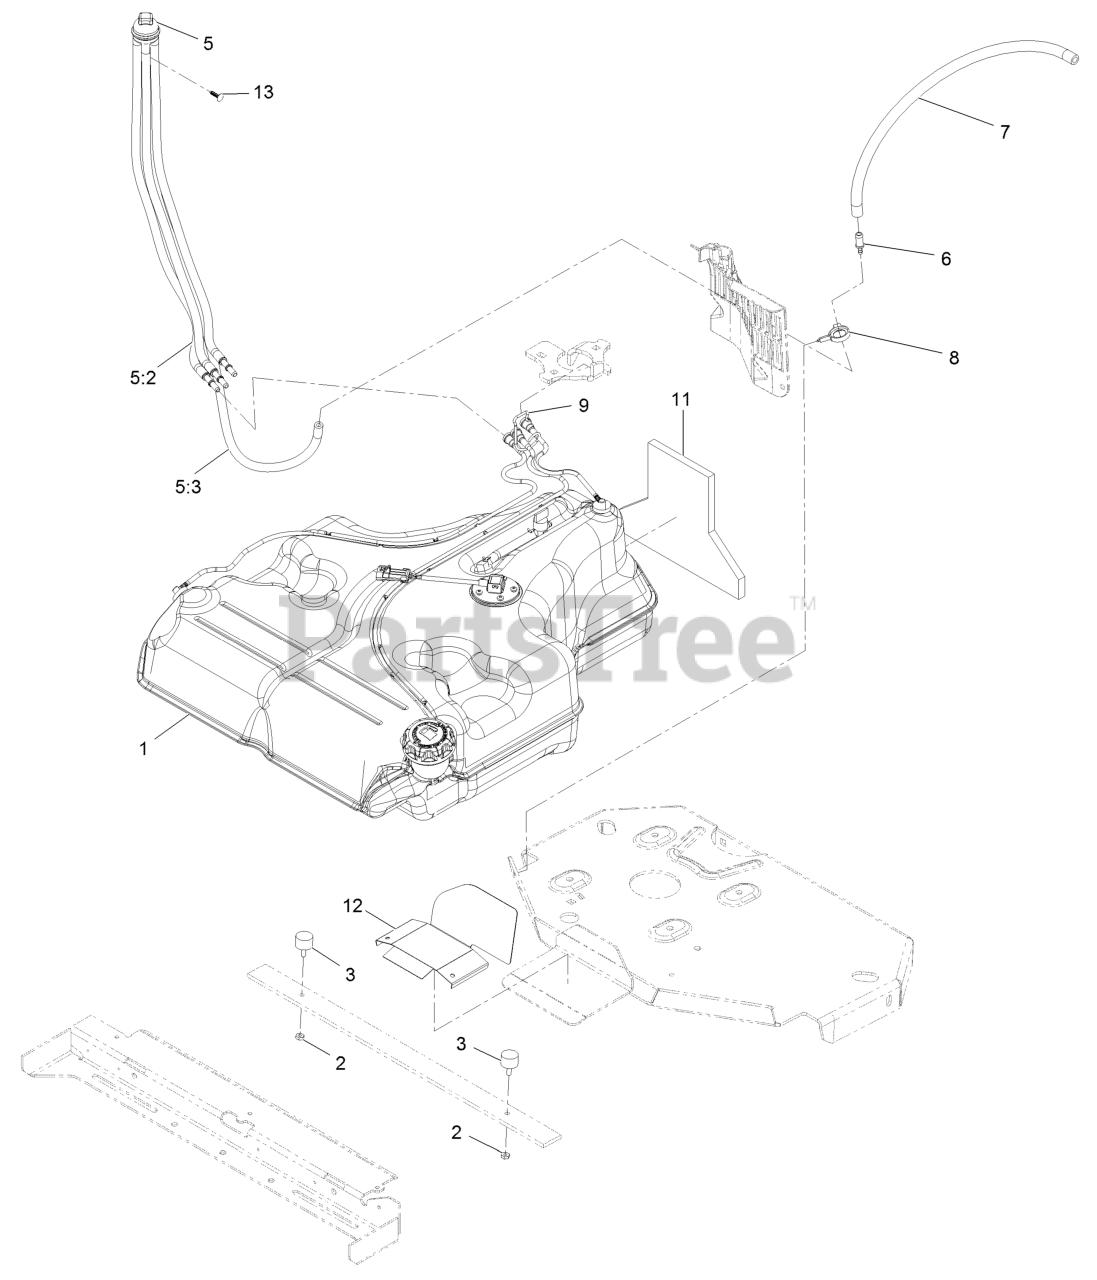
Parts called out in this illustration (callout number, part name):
2	NUT-JAM
5	FUEL MANIFOLD VENT ASM
5:2	HOSE-FUEL
5:3	HOSE-FUEL
6	FITTING-STRAIGHT
7	HOSE-FUEL
8	CLAMP-HOSE
9	RETAINER-LINE, VAPOR
11	INSULATION-FOAM, FUEL TAN
12	GUARD-EXHAUST
13	PLUG-PLASTIC
